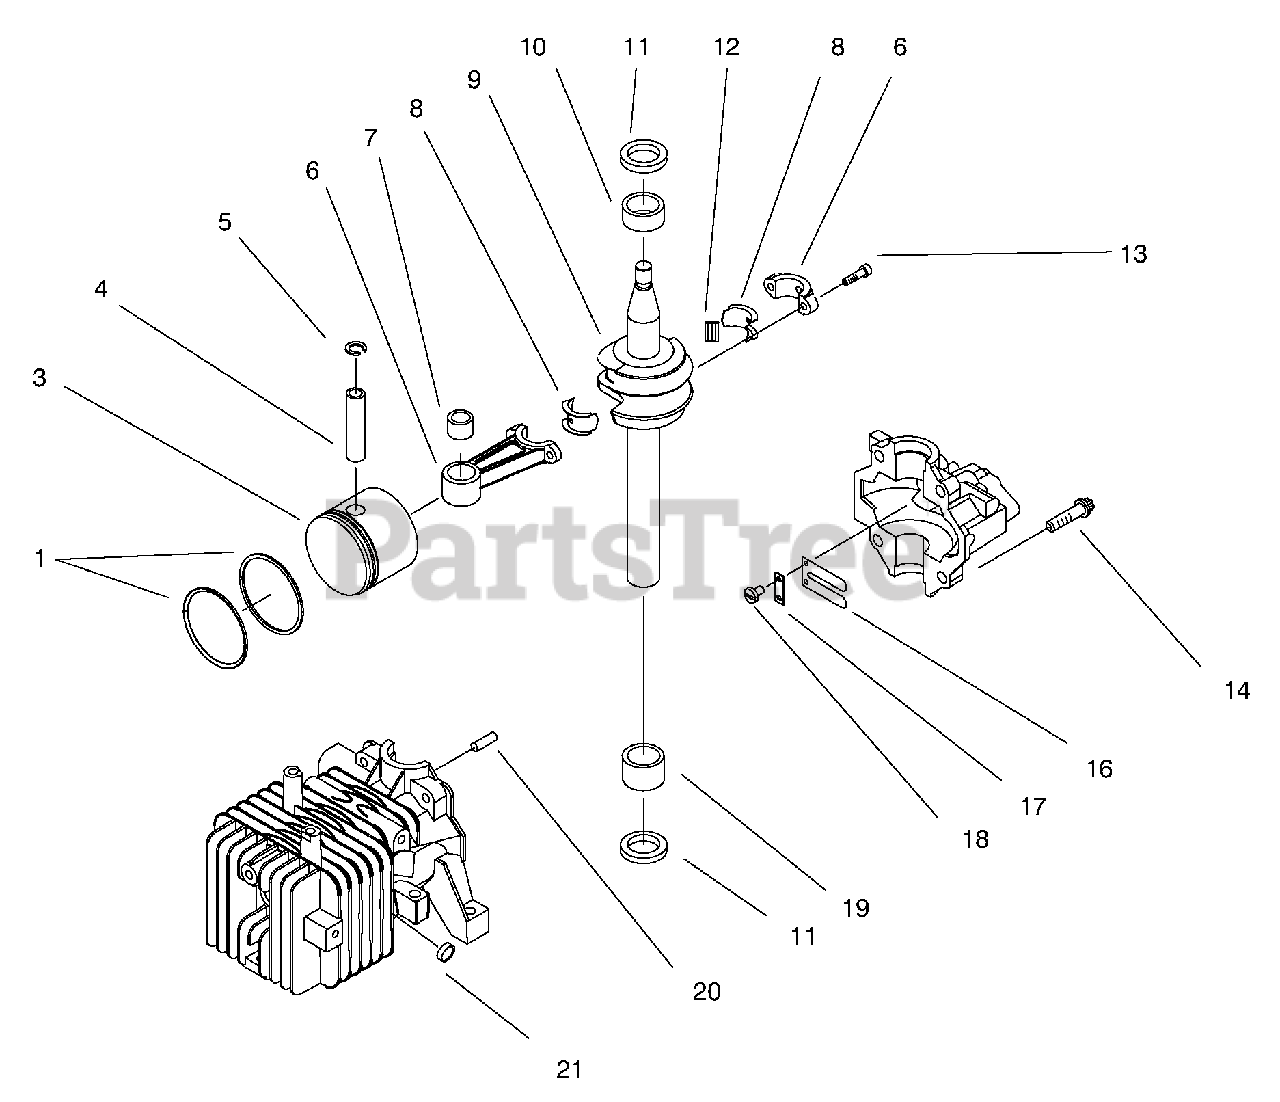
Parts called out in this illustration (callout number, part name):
1	Set-Rings, Piston
3	Piston & Connecting Rod (Incl. Ref. #1, 3-7 & 13)
4	Pin-Wrist
5	Ring-Retaining
6	Connecting Rod Assembly (Incl. Ref. #8, 12 & 13)
8	Liner-Split (Set of 2)
9	Crankshaft
10	Bearing-Upper Main
11	Seal-Oil
12	Bearing-Needle
13	Screw-Hex. Hd.
14	Screw-Hex. Washer Hd.
16	Reed-Carburetor
17	Reed-Backup Plate
19	Bearing-Needle
21	Plug-Core
22	Bearing-Thrust
23	Washer-Thrust
